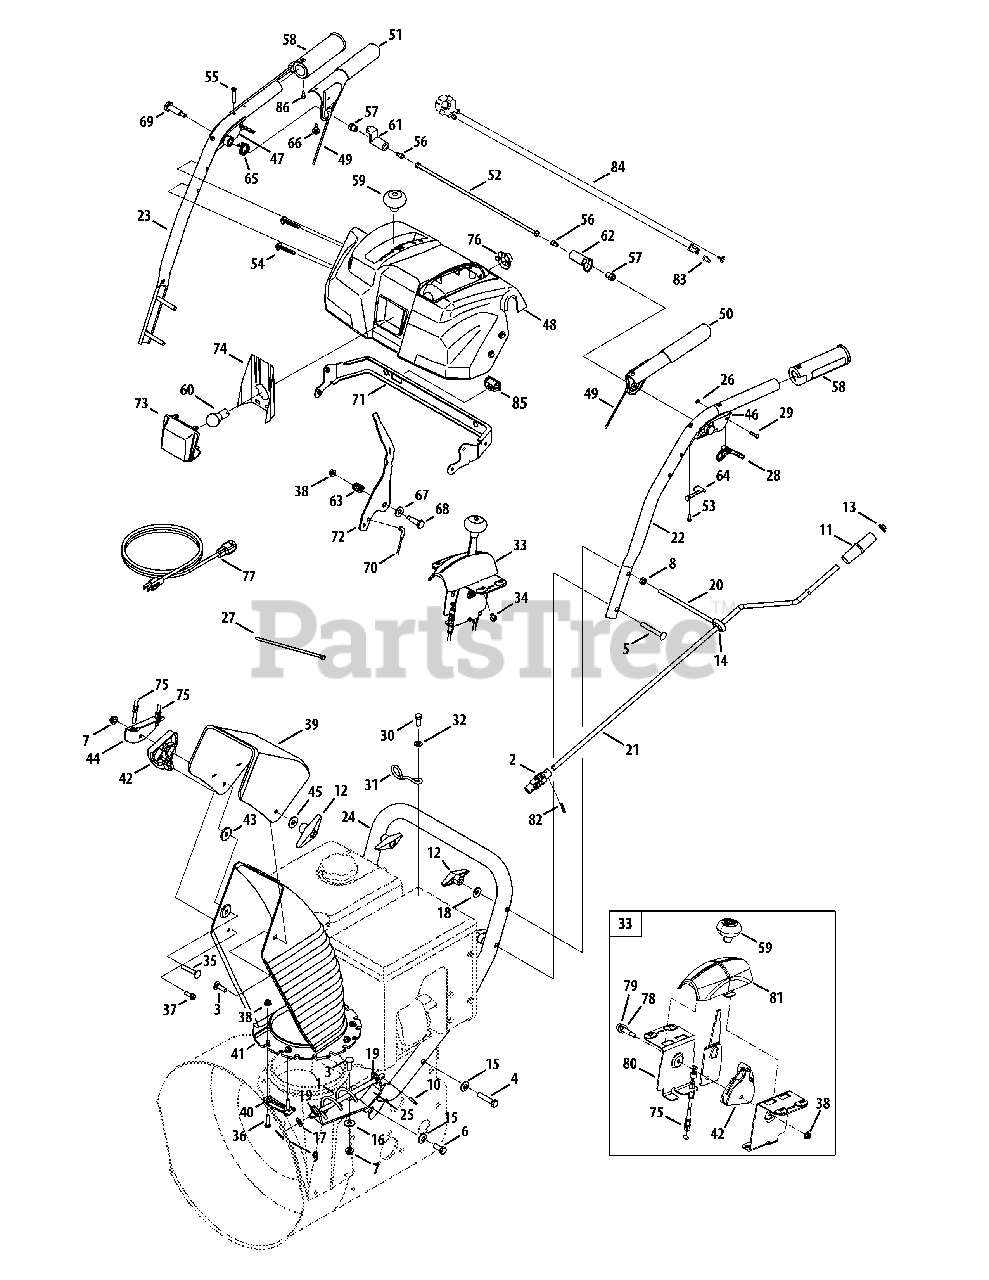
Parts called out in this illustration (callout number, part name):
1	Chute Crank Assembly
2	Joint Block Assembly
3	Screw, Carriage, 5/16-18 x 1.0
4	Screw, Hex, 3/8-16 x 2.00 Lock
5	Screw, Carriage, 5/16-18 x 2.5
6	Screw, Hex, 3/8-16 x 1.0 Lock, Gr5
7	Flange Lock Nut, 5/16-18
8	Hex Nut, 5/16-18
9	Pin, Bow-tie Cotter
10	Spring Pin
11	Knob, Crank
12	Wing Knob
13	Cap, Push, 3/8
14	Grommet, Rubber
15	Washer, Bel, .375 x .87 x .063
16	Washer, Flat, .349 x .879 .063
17	Washer, .375 x .738 x .063
18	Washer, Belleville, .34 x .872 x .06
19	Plastic Bushing, .380 I.D.
22	Handle, Upper - LH
23	Handle, Upper - RH
24	Handle, Lower
25	Chute Crank Bracket
26	Ring, Retainer
27	Cable Tie
30	Hex Head Screw, MB 1.25
31	Cable Guide
32	Flat Washer, .330 x .630 x .0635
33	2-Way Chute Control™ Assy
34	Hi-Lo Screw, 1/4-15 x 0.5
35	Bolt, Carriage, 5/16-18 x 1.75
36	Screw, 1/4-20 x 1.00
37	Hi-Lo Screw, 1/4-15 x .75
38	Flange Lock Nut, 1/4-20
39	Upper Chute
40	Chute, Flange Keeper
41	Lower Chute
42	Chute Tilt Cable Guide
43	Flat Washer
44	Cable Bracket
45	Washer, Flat, .349 x .879
46	Handle Clutch Lock - LH
47	Handle Clutch Lock - RH
48	Handle Panel
49	Cable Assembly, Auger/Drive
50	Handle Engage Assy - LH
51	Handle Engage Assy - RH
52	Rod Ass’y, Clutch Lock Pivot
53	Screw, #8-16 x 0.50
54	Screw, 1/4-20 x 1.625
55	Screw, #10-24 x 0.375
56	Screw, 1/4-20 x.375
57	Shoulder Nut, 1/4-20
58	Heated Grip
59	Shift Knob
62	Clutch Lock Cam
63	Compression Spring
64	Clutch Lock Spring
65	Torsion Spring
66	Rubber Bumper
67	Flat Washer, .385 x .87 x .06
68	Shoulder Screw
69	Shoulder Screw, 1/4-20 x 1.345
70	Speed Selector Cable
71	Panel Bracket
73	Lens Panel
74	Reflector Label
75	Cable, Chute Tilt
76	Light Socket
77	Extension Cord, 110V
78	Washer, Spring, .39 x .625 x .012
79	Screw, Shoulder, .31 x .995:1/4-20
80	Bracket, Mounting
81	Cover, Tilt Cover
82	Internal Cotter Pin
83	1/4-20 x .50
84	Wire Harness
85	Heated Grip Switch
86	Screw, #10-16 x .625
